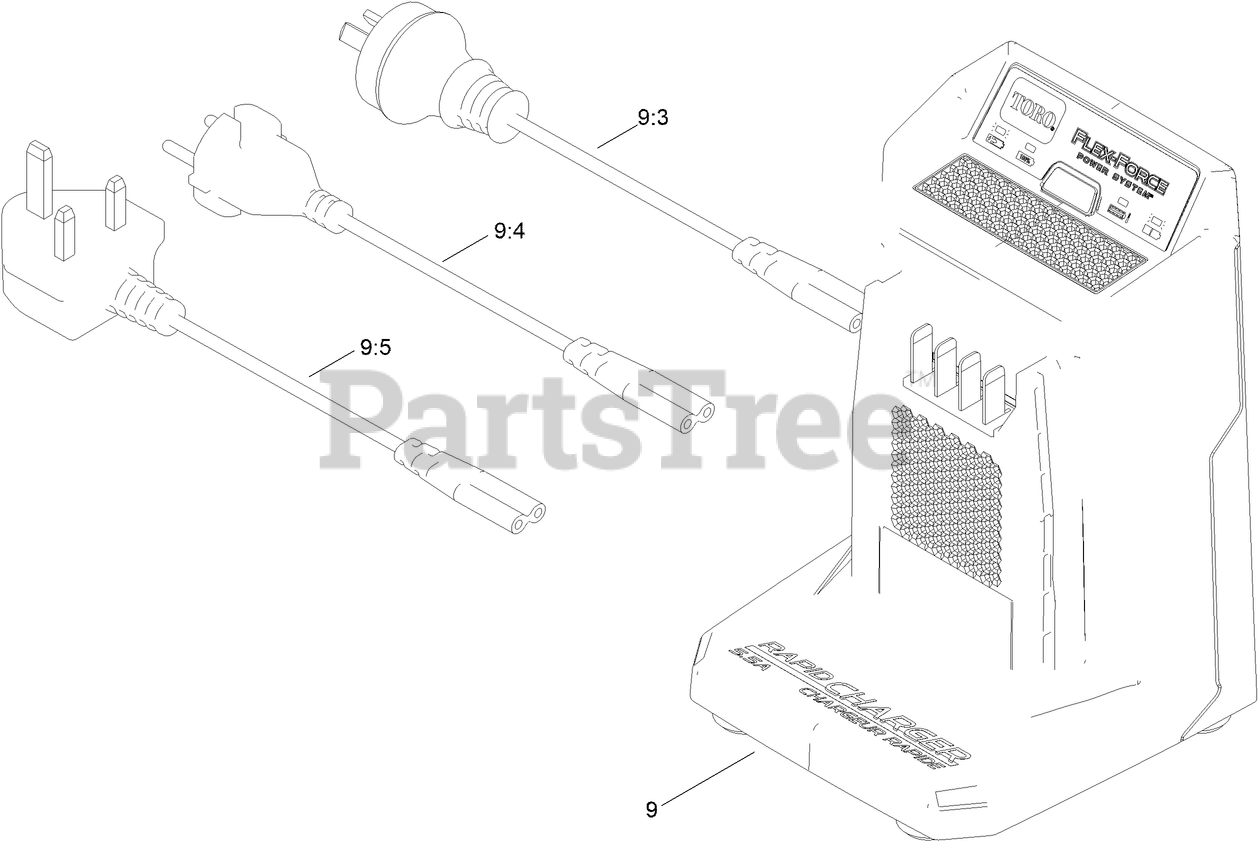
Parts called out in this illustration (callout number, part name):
9:3	CORD-CHARGER, AU/NZ
9:4	CORD-CHARGER, CE
9:5	CORD-CHARGER, UK
